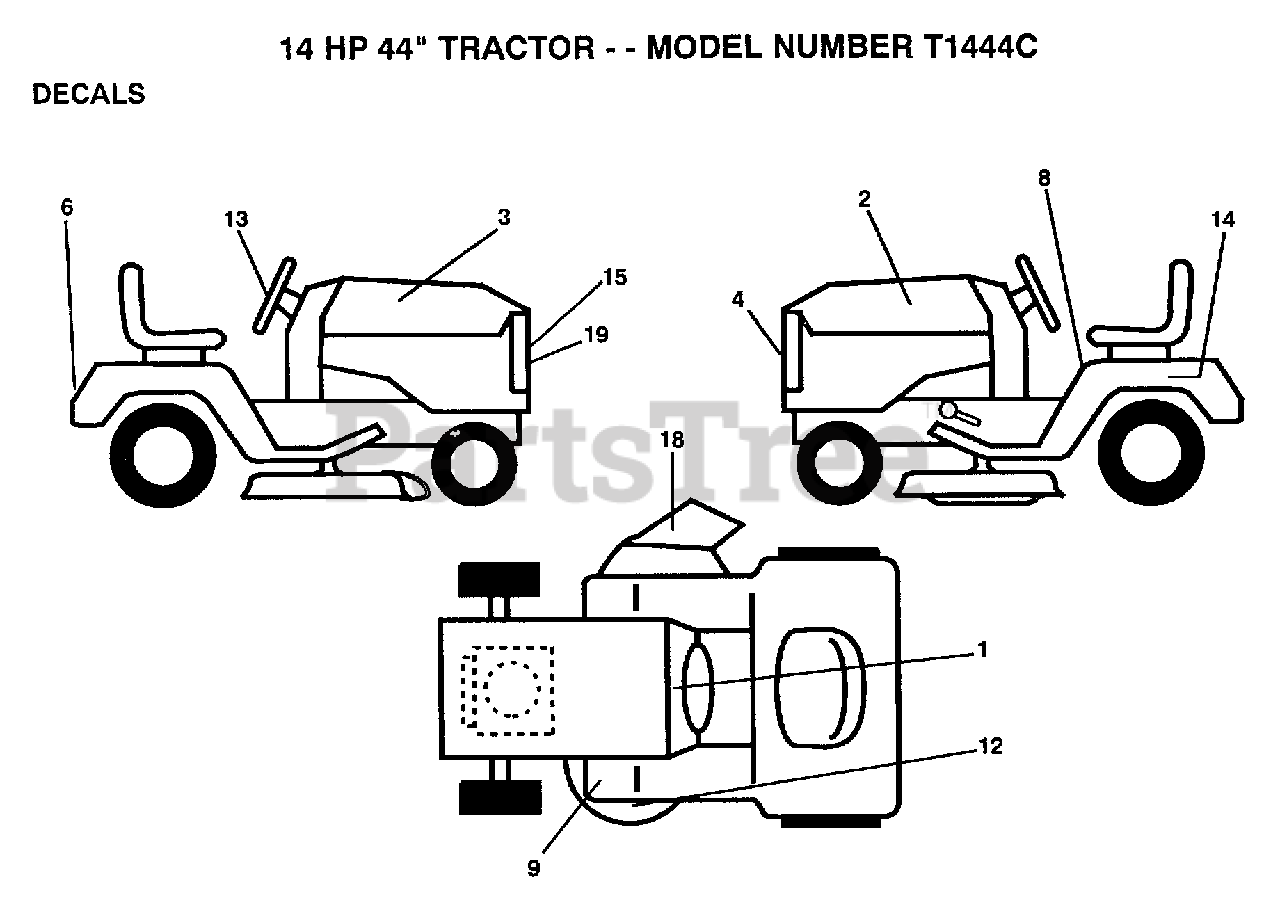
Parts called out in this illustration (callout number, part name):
2	DECAL, HOOD L.H.
3	DECAL, HOOD R.H.
4	"DECAL,GRILL"
6	"DECAL,FENDER T"
9	DECAL T
12	DECAL YT
13	"DECAL,STR WHL T"
14	DECAL
15	DECAL.STRIPE.GR
18	DECAL WARNING
19	"DECAL,GRILL HP T"
